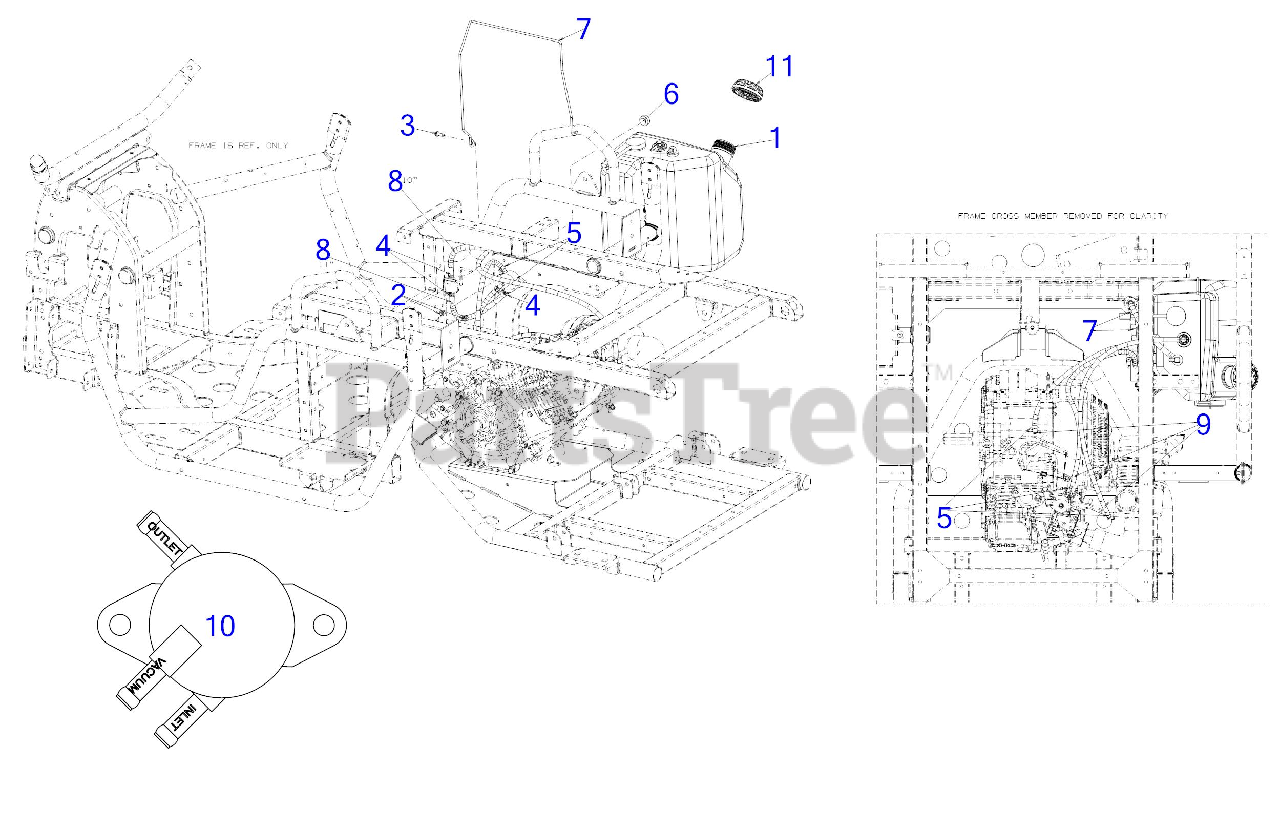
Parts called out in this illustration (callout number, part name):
1	FUEL TANK ASSEMBLY
2	SCREW M6-1 x .625
3	SCREW 1/4-20 x .750
4	HOSE CLAMP 1/20
5	HOSE CLAMP 0.470
6	RUBBER BUMPER 1.000 x .313
7	FUEL TANK RETENTION ROD
8	FUEL HOSE LOW PERMEATION
9	FUEL HOSE LO PERMEATION 7/32 YELLOW
10	ENGINE FUEL PUMP
11	FUEL CAP W/TETHER
